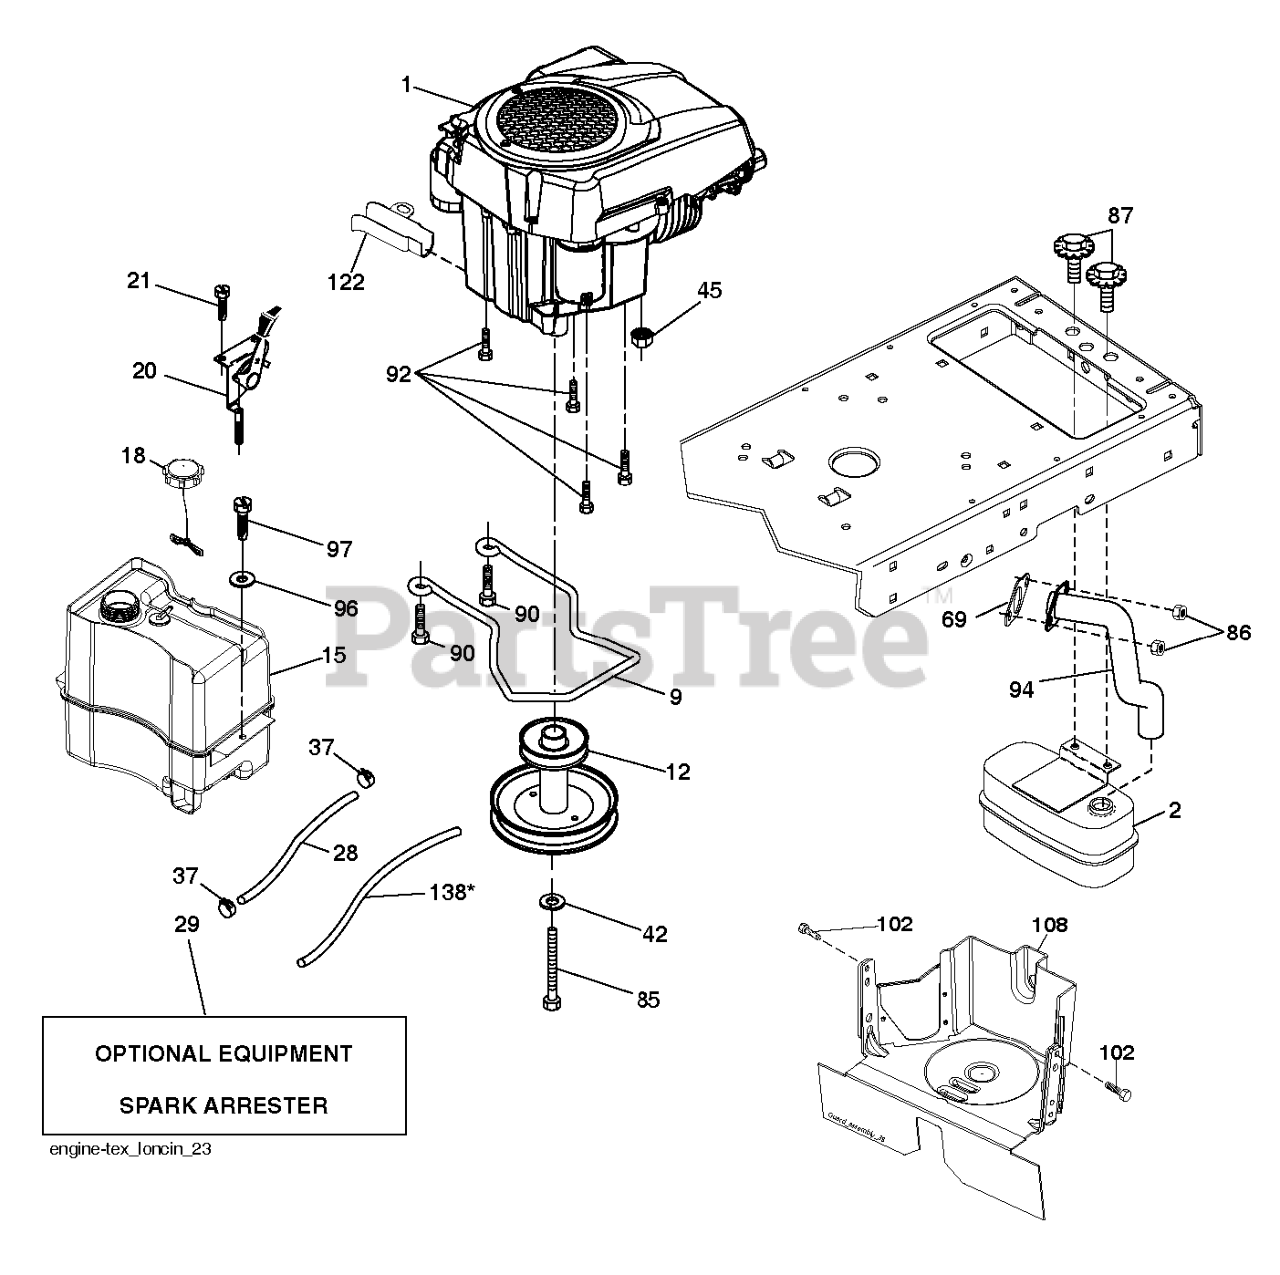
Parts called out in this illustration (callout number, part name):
2	MUFFLER.ASM.SINGLE
12	ENGINE.PULLEY
15	FUEL.TANK.ASM.NON-EPA
15	Tanks
18	CAP ASM.FUEL.2.25"FR.
20	CONTROL.TH/CK.C.
28	LINE.FUEL.20"FRONT.EMI
29	KIT.SPARK ARRESTOR 794945 B&S
37	HOSE CLAMP
45	NUT HEXAGON WITH FLANGE, SERRA
69	GASKET GASKET.EXHAUST.LONCIN 3
85	BOLT.HEX.7/16-20X4.GR5.1.5BLUE
86	NUT.HEX.FLANGE.TOPLOCK
87	BOLT.5/16-18UNCX3/4 W/SEMS.BLK
90	SCREW 3/8-16X1
92	SCREW 3/8-16X1
94	TUBE TUBE.EXHAUST.LONCIN 452.T
97	SCREW HEXWSHR 1/4-20X3/4
108	COVER ENGINE PULLEY COVER WITH
122	EXTENSION DRAIN OIL
